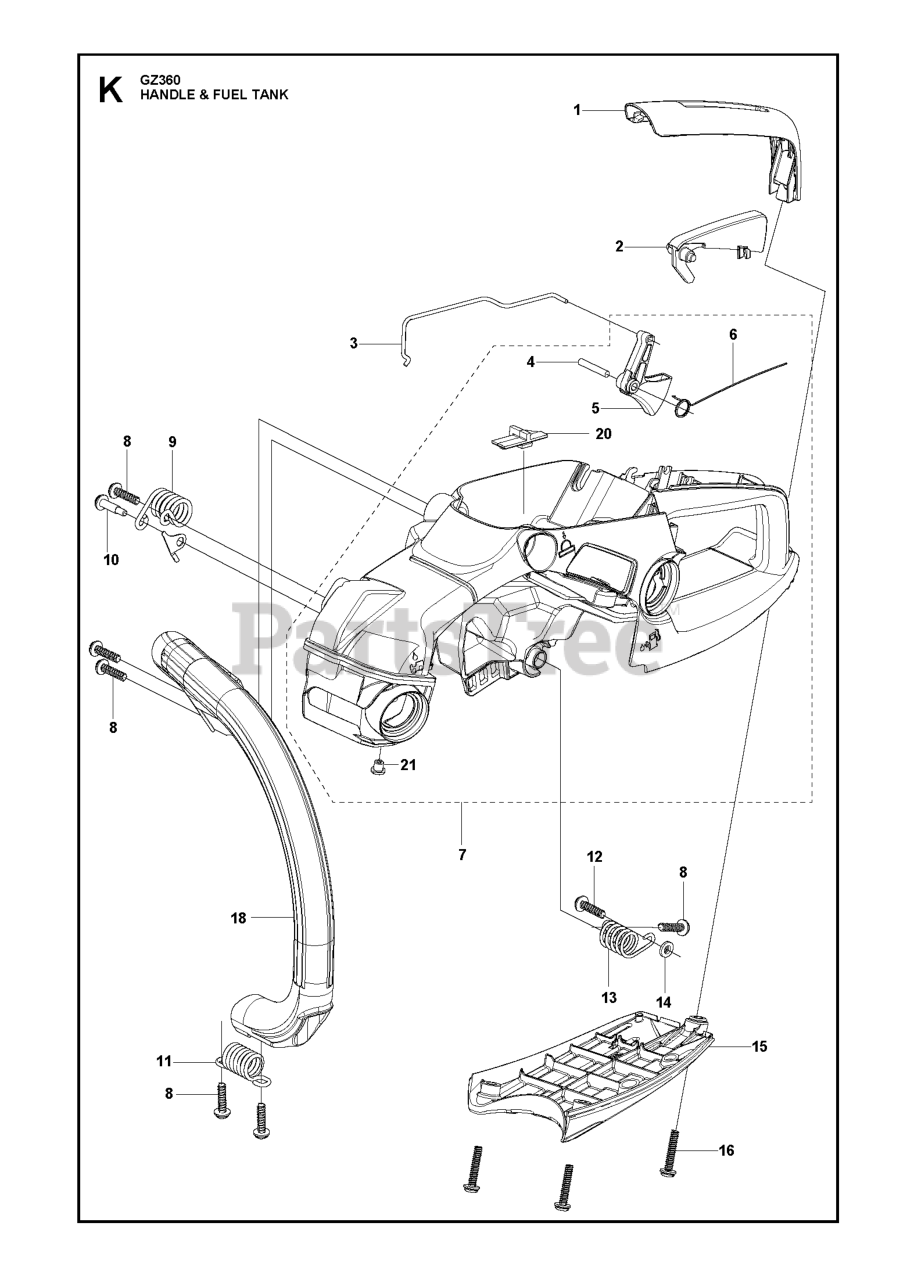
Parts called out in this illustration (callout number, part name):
1	COVER GRIP GZ3500L
2	THROTTLE LOCKOUT ZENOAH BLACK
3	THROTTLE ROD 436/GZ3500L
4	PIN 8488B42400
5	THROTTLE LEVER
6	SPRING
7	HANDLE ASSY GZ360EZ
9	SPRING FRONT 439
11	SPRING FLYWHEEL SIDE
12	SCREW (RPLS 267132210)
13	SPRING, PTO
14	SPACER Z114283110
15	COVER HANDLE BLACK
18	FRONT HANDLE GZ3500L
20	GROMMET R HANDLE
